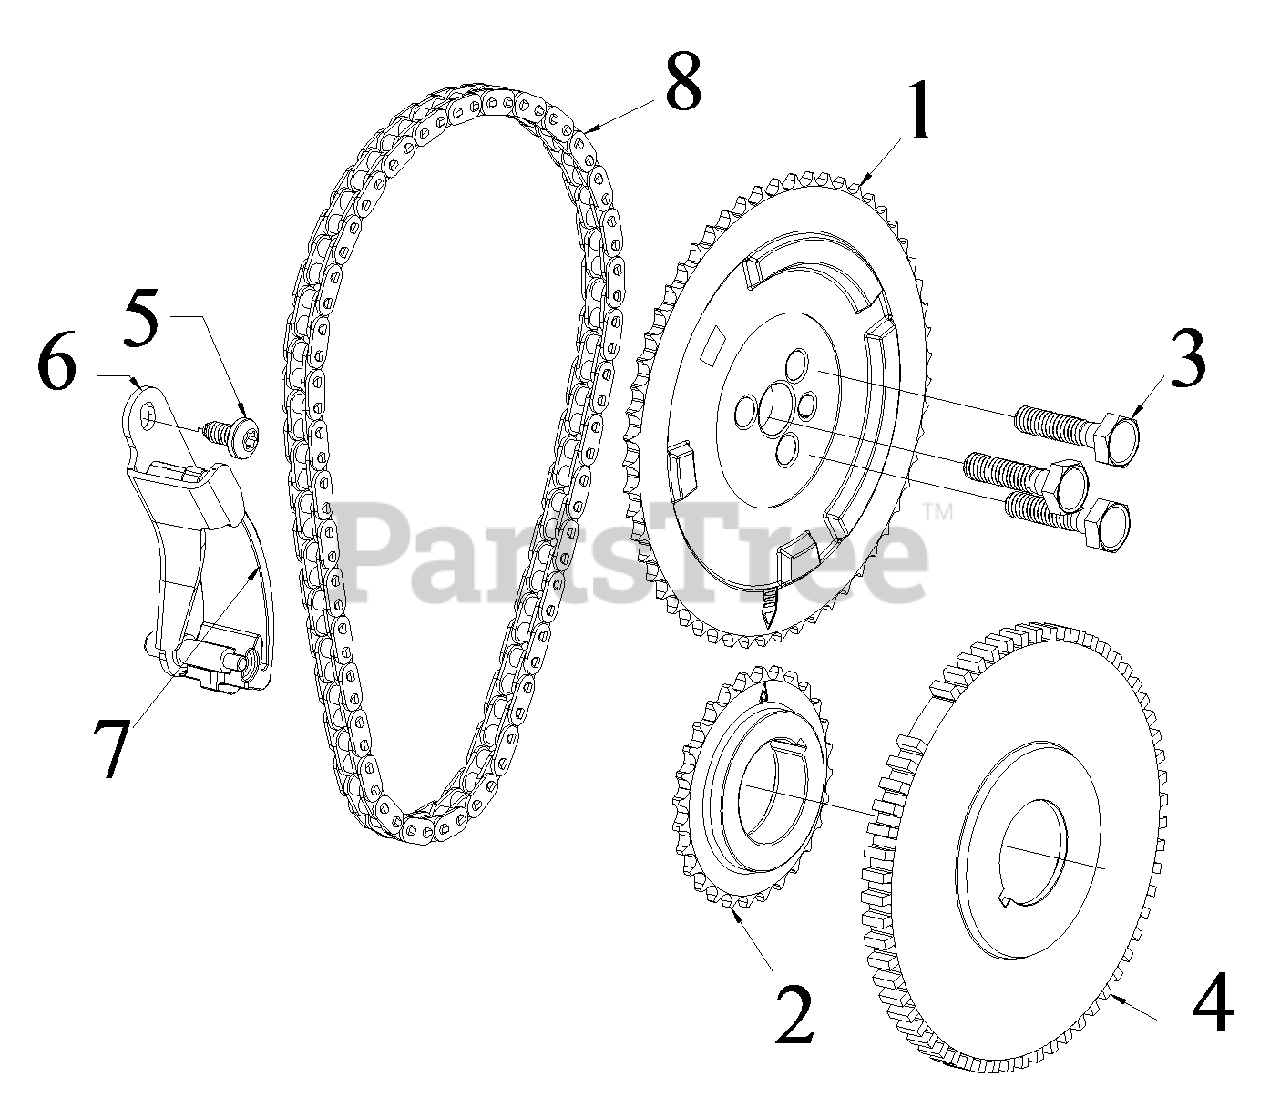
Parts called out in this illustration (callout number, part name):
1	SPROCKET, CAM/CRANK KIT
2	SPROCKET, CRANKSHAFT
3	BOLT, CAMSHAFT SPROCKET
4	RING, CRANKSHAFT POSITIONER
5	BOLT, BALANCER SHAFT RETAINER
6	GUIDE, TIMING CHAIN
7	GUIDE, TIMING CHAIN
8	CHAIN, TIMING
